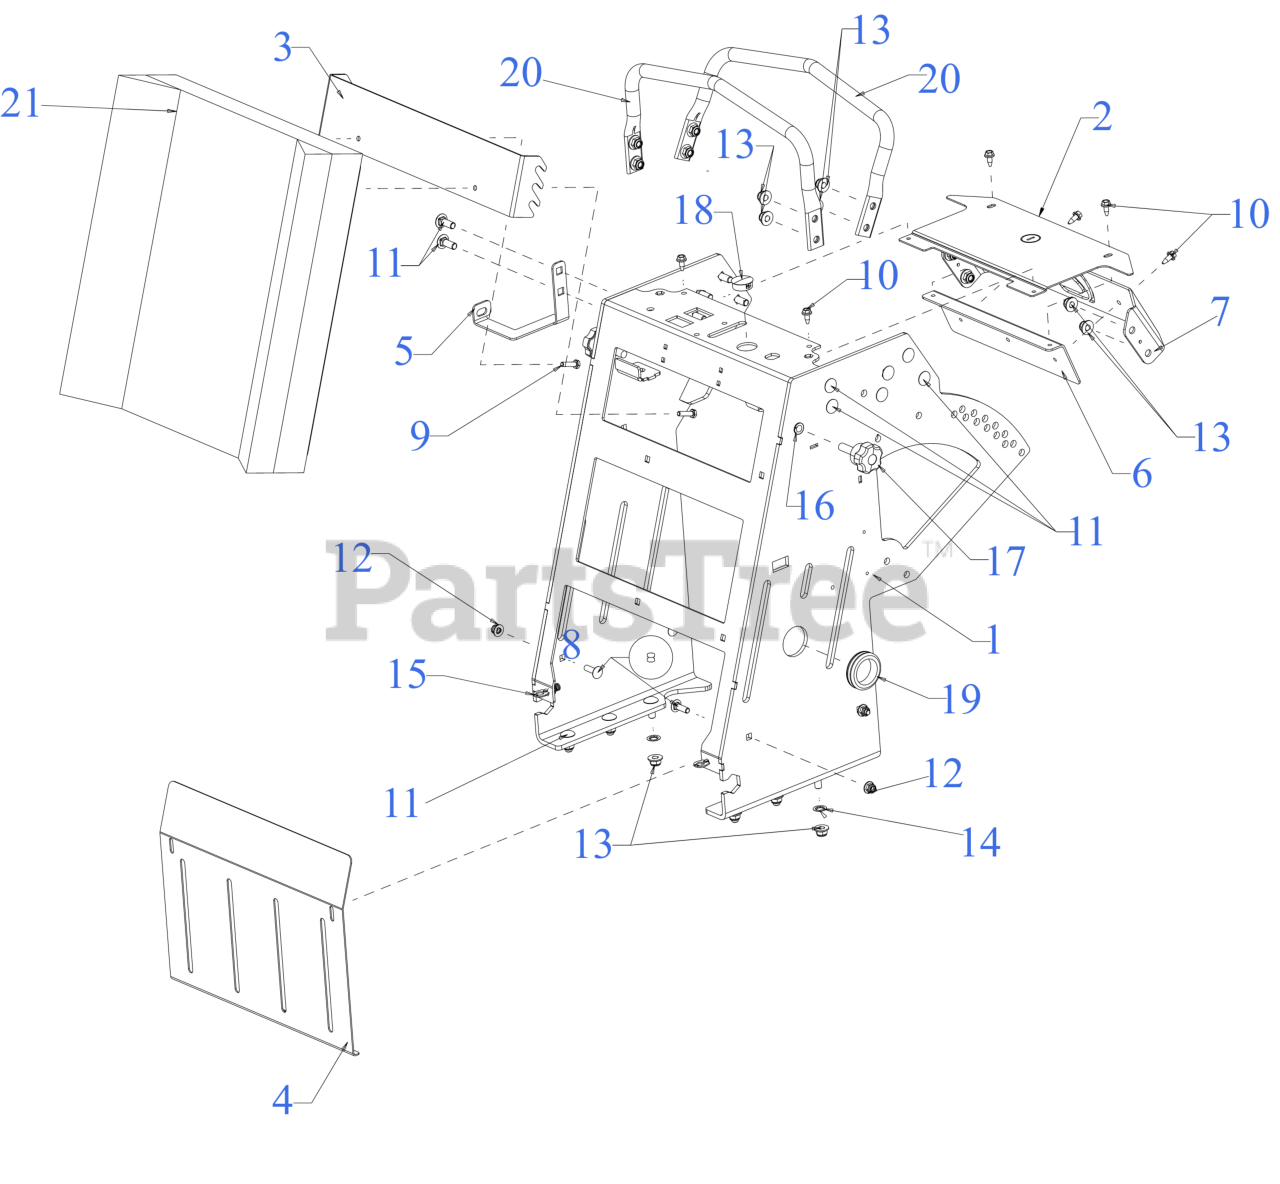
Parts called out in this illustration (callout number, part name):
1	CONTROL BASE
2	DASH PANEL
3	LEG PAD BRACKET
4	REAR COVER BRACKET (LOWER)
5	FUEL TANK BRACKET (UPPER)
6	DASH SUPPORT BRACKET
7	CONTROL BASE (FRONT)
8	CARRIAGE BOLT 5/16-18 x 1.00
9	SCREW 1/4-20 X1.00 GR5
10	SCREW 1/4-20X.625
11	CARRIAGE BOLT 3/8-16 x 1.00 GR5
12	FLANGE LOCK NUT 5/16-18
15	PANEL LATCH
16	RIV NUT 3/8-16
17	SEAT ADJUST KNOB 3/8-16 x 1.50
18	PANEL PLUG
19	RUBBER GROMMET (1.50X2.13X.563)
20	CRUISE TUBE
